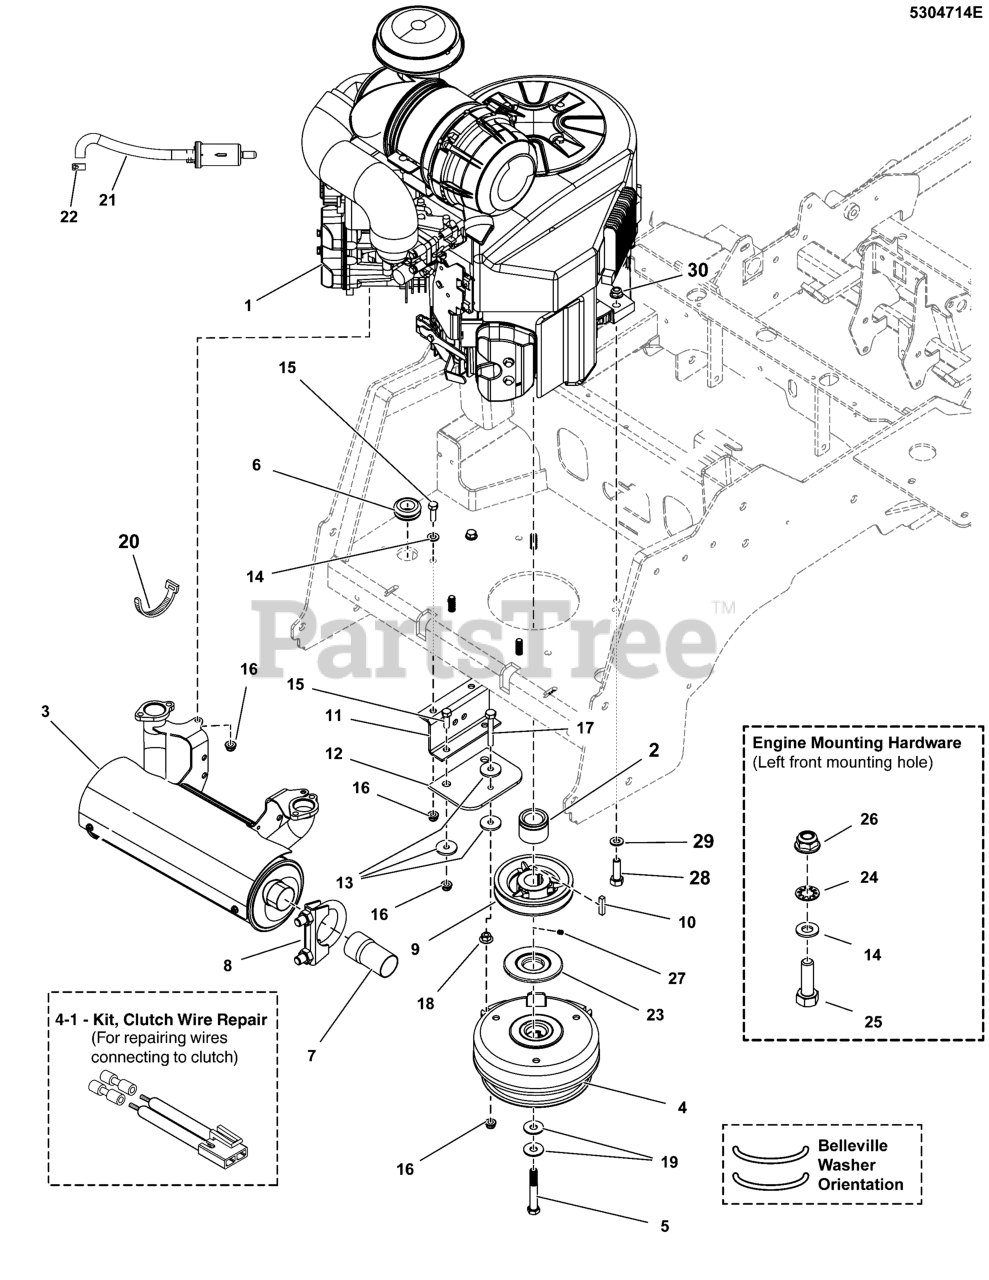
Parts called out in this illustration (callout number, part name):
2	SPACER, 1.13 X 1.75 X
3	MUFFLER
4	CLUTCH
4-1	KIT, CLUTCH WIRE REPAIR
5	BOLT, CRANKSHAFT
6	GROMMET, 7/8"ID
7	PIPE, EXHAUST
8	CLAMP, MUFFLER
9	PULLEY, 4.75 OD X 1-1
10	KEY, 1/4 SQ X 1-1/4
11	ANCHOR, CLUTCH
12	CLUTCH ANCHOR PAD
13	WASHER, .34 X 1.25 X
14	WASHER
16	NUT
17	BOLT, 5/16-18 X 2-1/4
18	NUT, 5/16-18 HEX SERR
19	BELLEVILLE WASHER
20	TIE WRAP, 5-1/2" LONG
21	HOSE/FILTER ASSEMBLY
22	CLAMP, HOSE
23	GUARD
24	WASHER, 5/16" INT. TO
27	SET SCREW, 5/16-18 X
28	BOLT, 3/8-16 X 1-3/4"
30	NUT, 3/8-16 HEX NYLOCK
